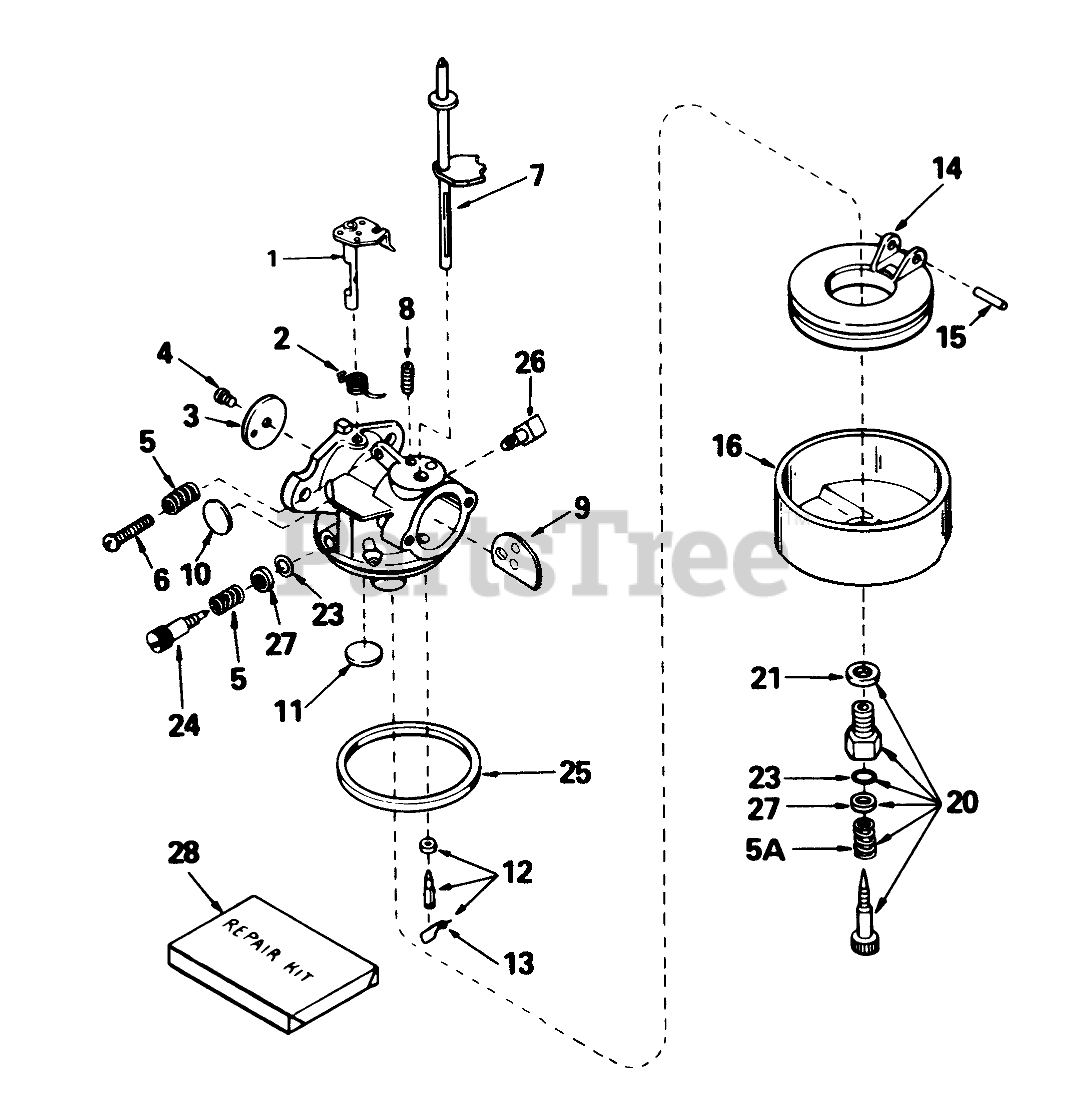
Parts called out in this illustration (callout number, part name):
1	Throttle Shaft and Lever ASM
2	Spring-Return, Throttle
3	Shutter-Throttle
4	Screw-Shutter
5	Spring-Tension
6	Screw-Throttle Crack Screw / Idle Speed
7	Shaft-Choke
8	Spring-Positioning, Choke
9	Shutter-Choke
10	Plug-Welch, Idle Mixture Well
11	Plug-Welch, Atmospheric Vent
12	Inlet Needle-Seat & Clip Assy. (Incl. Ref. #13)
13	Clip-Spring
14	Float
15	Shaft-Float
16	Bowl-Float (no drain)
20	Adjustment Screw Assy.-Main (Incl. Ref. #5A, 21, 23 & 27)
21	Washer-Bowl Nut
23	"O"Ring
24	Screw, Idle Adj.
25	O Ring-Bowl, Float
26	Fitting-Fuel
28	Kit-Repair
